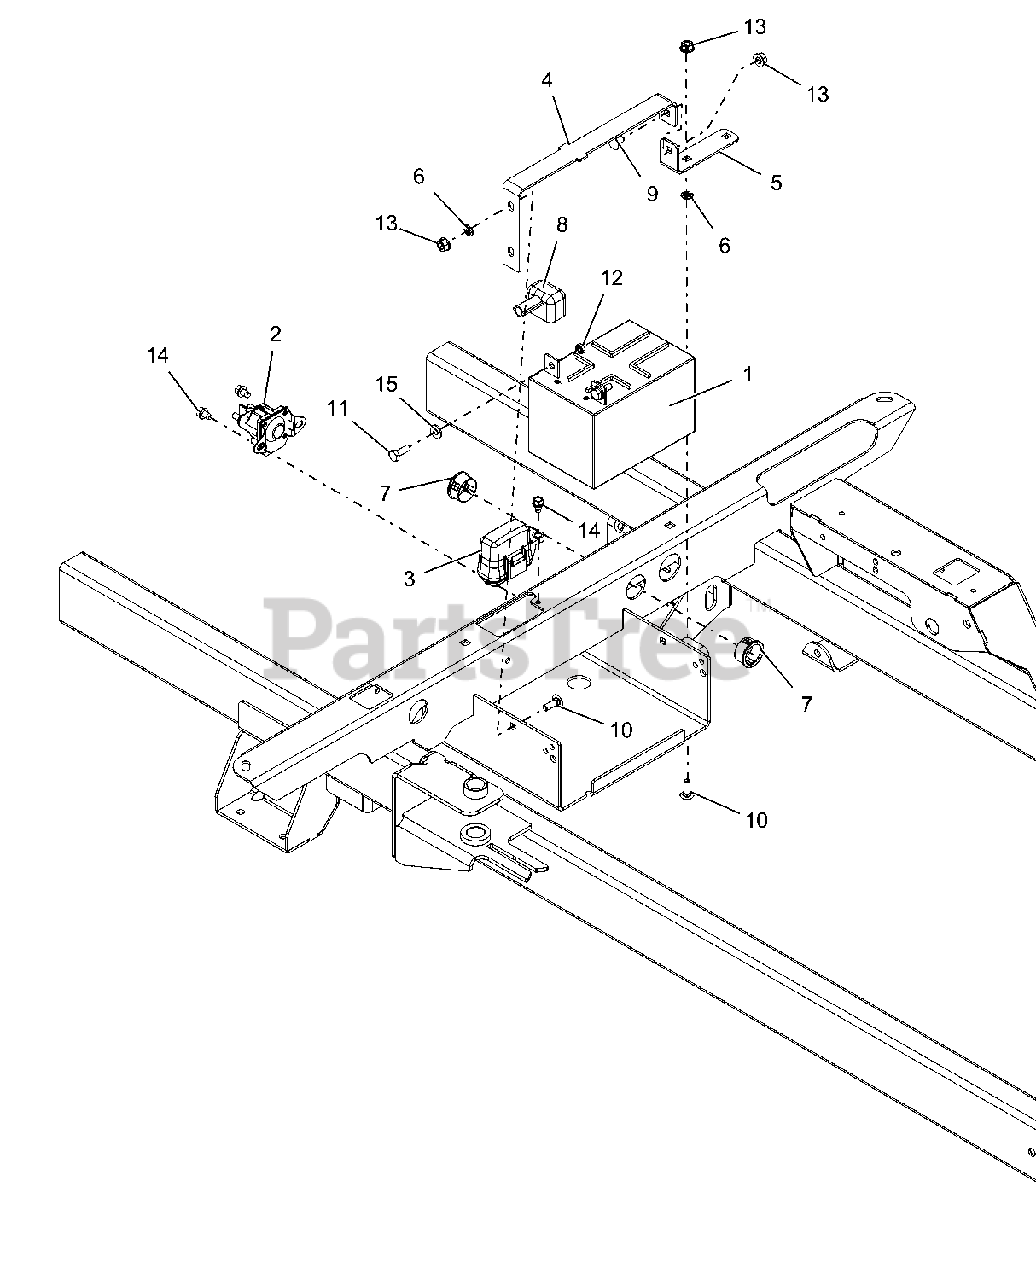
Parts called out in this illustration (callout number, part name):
1	BATTERY, 12V 12A-190CCA
2	SOLENOID, STARTER (SEALED)
4	BRKT, BATTERY HOLD-DOWN
5	BRKT, BATTERY HOLD DOWN
6	NUT-PUSH .25X.50 O.D.
7	BSHG, PANEL SNAP .937X1.11X.56
8	INSULATOR
9	@BLT-RDHDSQNK .25-20X.50 G5YZ
10	@BLT-RDHDSQNK .25-20X.75 G5YZ
11	@BLT-HEX .25-20X.75 GR5 YWZC
12	NUT, 10-24 KEPS
13	@NUT-LK-TOP-FLG .25-20 YWZC
14	@SCR-TAP .25-20X.37 HWH YWZ TR
15	@WSHR-FL-STL.281X.62X.065 YWZC
